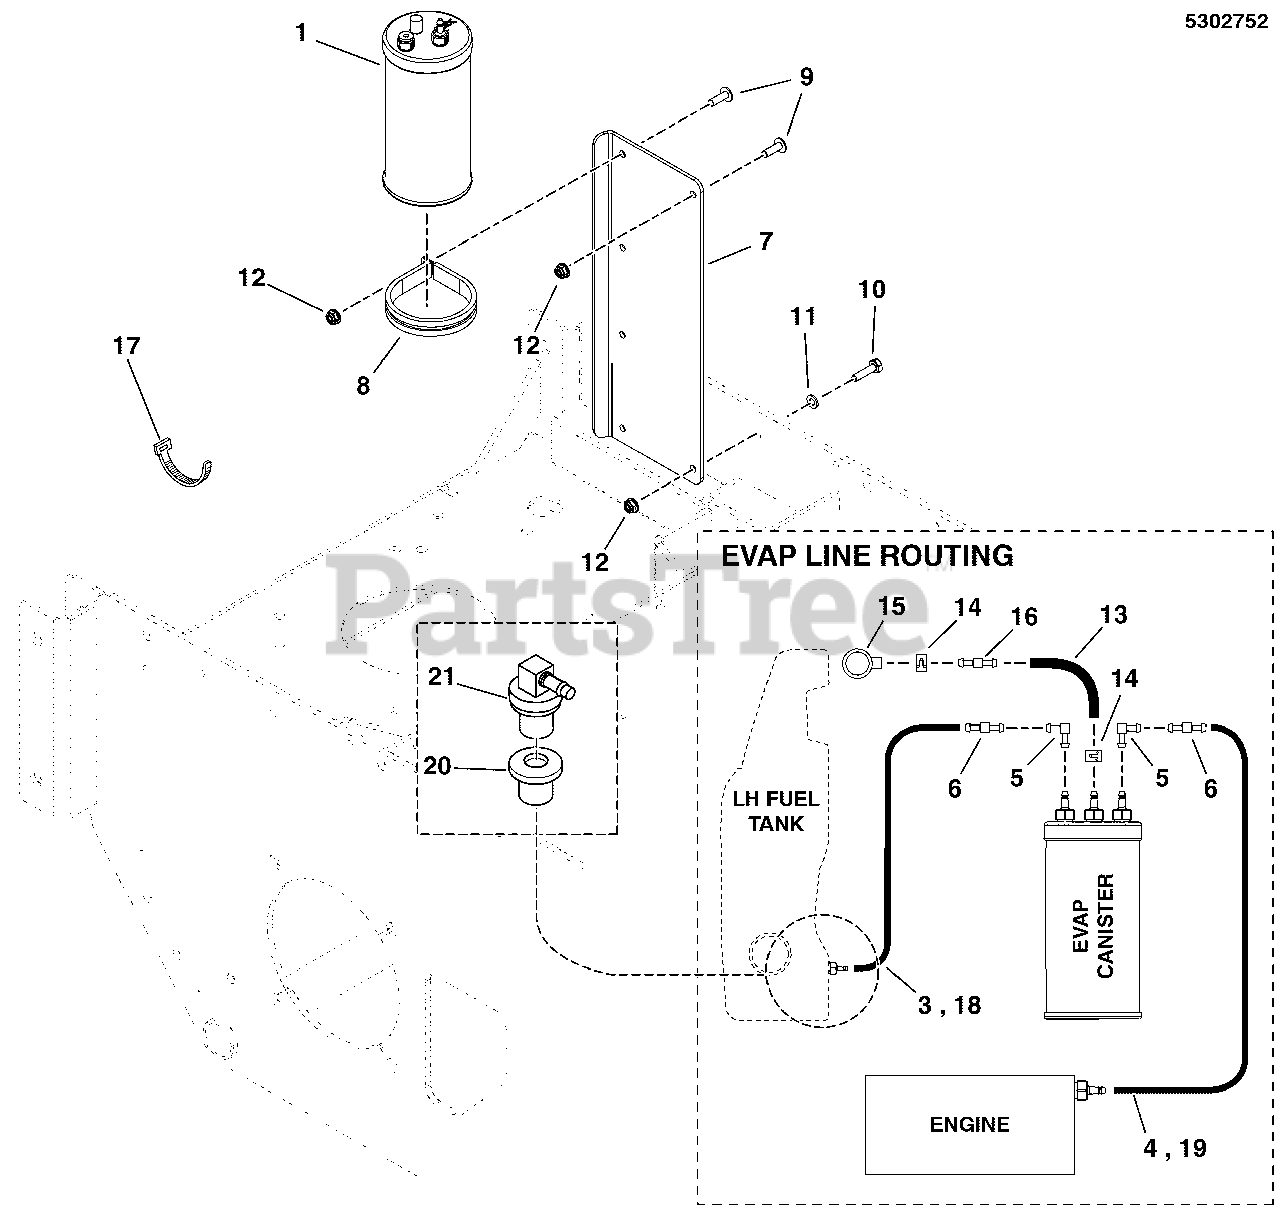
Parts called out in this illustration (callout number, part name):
1	CNSTR, CARB, 6 GAL
2	DECAL, EPA CERT, ZTRS
3	HOSE, VAPOR, 5MM ID, 11.00 LG
4	HOSE, VAPOR, 5MM ID, 31.00 LG
5	FITTING, 90 DEG, 3/16X3/16, SANTOPRENE
6	FITTING, STRAIGHT, 3/16X3/16, PLASTIC
7	MOUNT, CAN, SIDE - BLK
8	CLAMP, 3" ID, CUSHIONED, STAINLESS
10	BOLT, 1/4-20 X 1" GD5 CZ
11	WASHER, 1/4 SAE
12	NUT, 1/4-20 HEX NYLOCK FLANGE
13	HOSE, FORMED, EVAP CANISTER
14	CLAMP, HOSE
15	DUST FILTER, CANISTER (SV)
16	FITTING, STRAIGHT, 10MMX10MM, PLASTIC
17	TIE, SELF-LOCKING, 15"
18	HOSE, VAPOR, 5MM ID, 11.00 LG
19	HOSE, VAPOR, 5MM ID, 42.00 LG
20	GROMMET (SV)
21	REMOTE VENT ASSEMBLY
